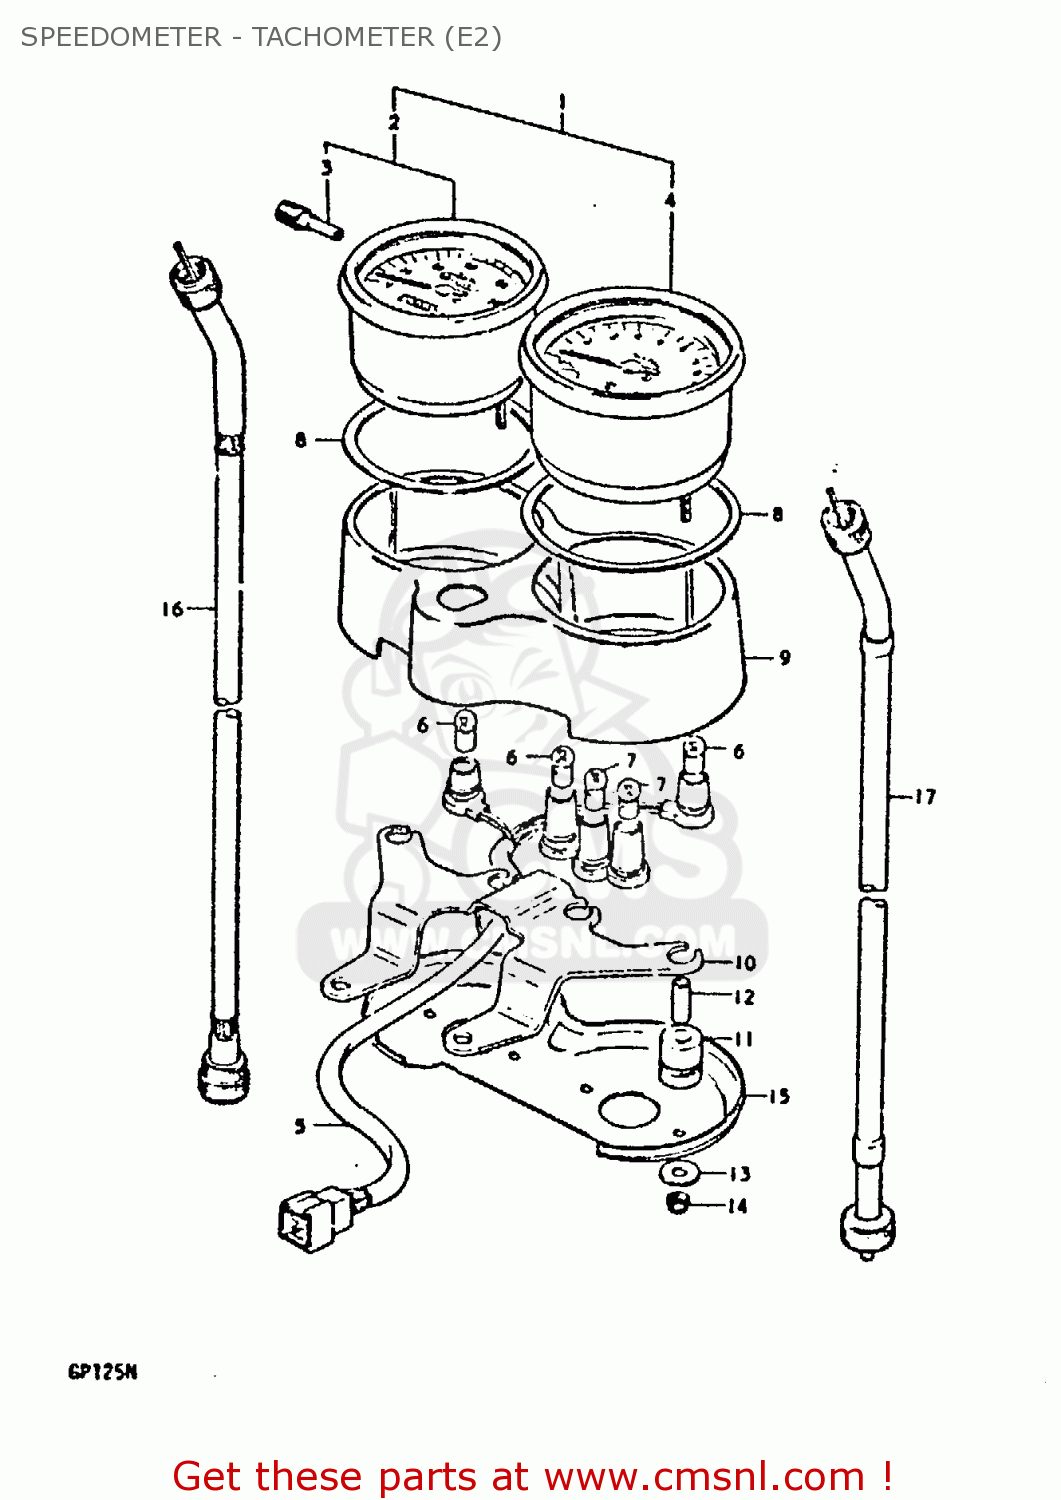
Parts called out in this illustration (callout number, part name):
1	SPEEDO/TACHOMETER ASSY
2	SPEEDOMETER
3	KNOB,TRIP METER
4	TACHOMETER ASSY
5	SOCKET
6	BULB(6V1.7W,STANLEY,A61A)
7	BULB(6V/3W)
8	GASKET, METER
9	CASE, METER
10	BRACKET
11	CUSHION
12	SPACER
13	WASHER,METER
14	NUT
15	UNDER PLATE
16	CABLE ASSY, SPEEDOMETER
17	CABLE ASSY, TACHOMETER
